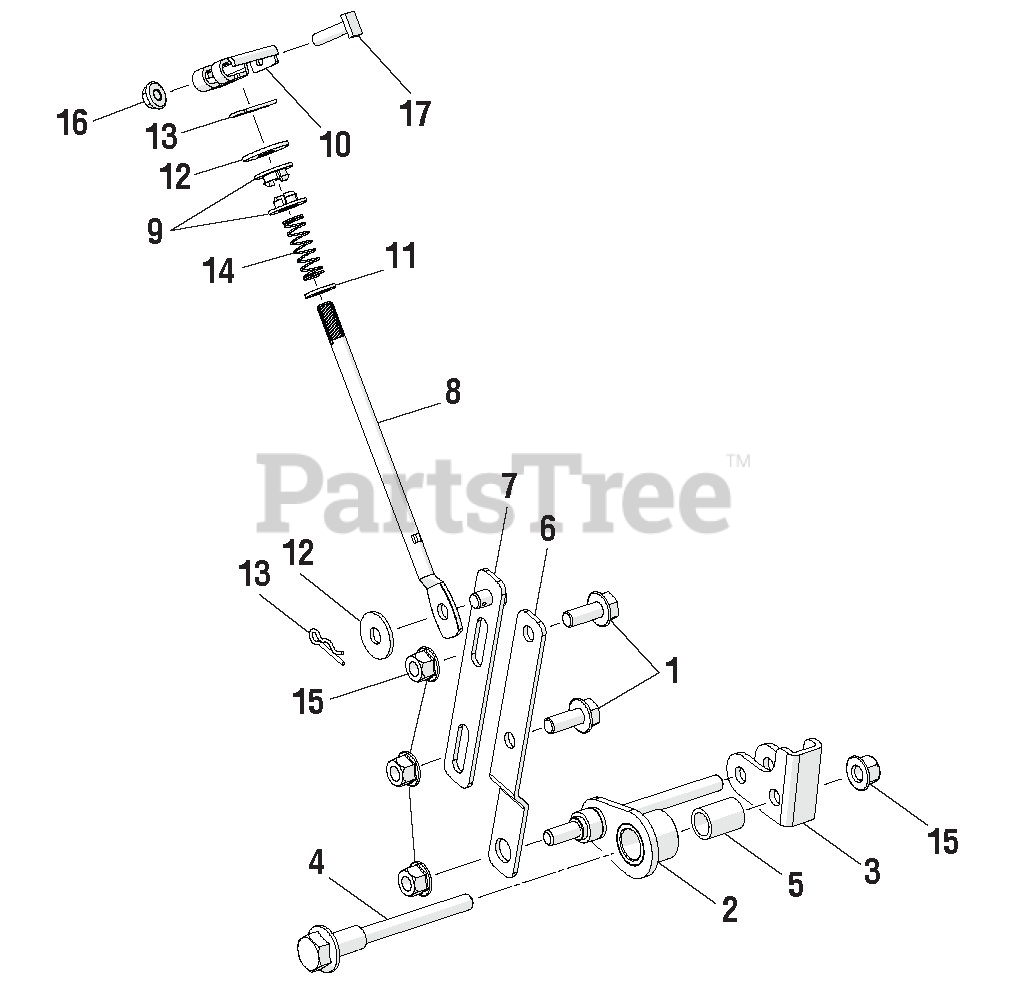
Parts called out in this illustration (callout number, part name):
1	Flange Bolt (M8 x 20 mm, Hex Hd.)
2	Pivot Bracket
4	Center Step Bolt
5	Nylon Sleeve
6	Lower Connecting Plate
7	Upper Connecting Plate Assembly
8	Upper Rod
9	Spring Capture Bushing, Nylon
10	Lever Bracket
11	Washer (OD16 x ID8.4 x 1.6t)
12	Washer (OD24 x ID8.4 x 2t)
13	Cotter Pin (8 mm)
14	Compression Spring
15	Flange Nut (M8)
16	Flange Nut (M6 )
17	Screw (M6 x 22 mm, Rectangle Hd.)
